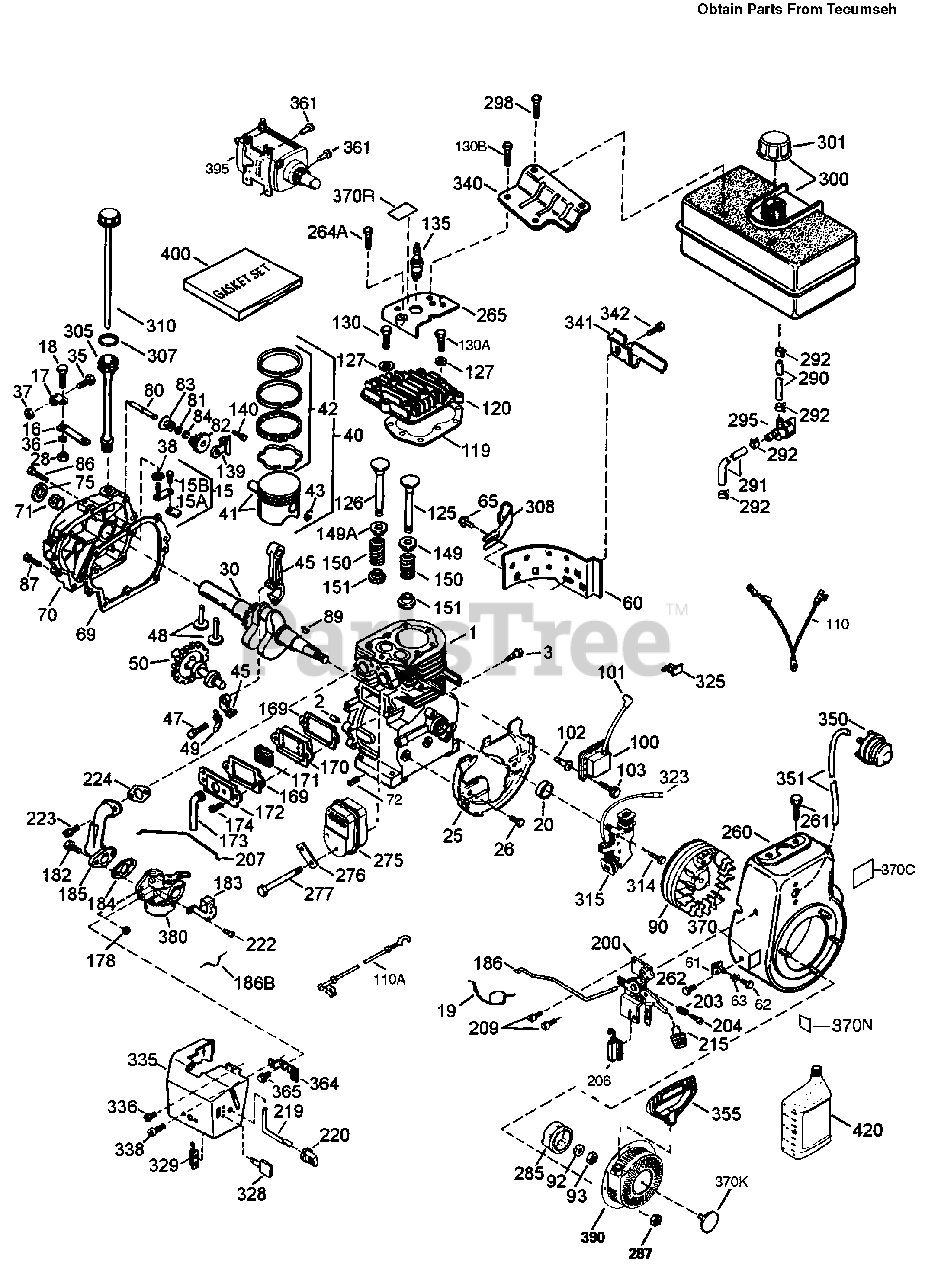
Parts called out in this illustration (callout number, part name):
1	Cylinder Asm (Incl. Ref. #2, 20, & 72)
2	Dowel Pin
15	Governor (Incl. Ref. #15A & 15B)
15A	Governor Yoke
16	Governor Lever
17	Governor Lever Clamp
19	Spring-Speed Control
20	Oil Seal
25	Blower Housing Baffle
28	Lock Nut
30	Crankshaft
36	Lock Washer
37	Lock Nut
38	Retaining Ring
40	Piston, Pin & Ring Set (Std.)
40	Piston, Pin & Ring Set (.010" OS)
41	Piston & Pin Asm (Std.)(Incl. Ref. #43)
41	Piston & Pin Asm (.010" OS)(Incl. Ref. #43)
42	Ring Set (Std.)
42	Ring Set (.010" OS)
43	Piston Pin Retaining Ring
45	Connecting Rod Asm (Incl. Ref. #47, & 49)
47	Connecting Rod Bolt
48	Valve Lifter
49	Oil Dipper
50	Camshaft (MCR)
60	Blower Housing Extension
61	Grommet Mounting Bracket
63	Grommet
69	Cylinder Cover Gasket
70	Cylinder Cover (Incl. Ref. #71, 75, & 80)
71	Crankshaft Bushing
72	Oil Drain Plug
75	Oil Seal
80	Governor shaft
82	Governor Gear Asm (Incl. Ref. #81)
83	Governor Spool
84	Retaining Ring
89	Flywheel Key
90	Flywheel (W/Ring Gear)
92	Lock Washer
93	Flywheel Nut
100	Solid State Ignition
101	Spark Plug Cover
102	Solid State Mounting Stud
103	Screw, Torx T-15
110	Ground Wire
110A	Ground Wire
119	Cylinder Head Gasket
120	Cylinder Head
125	Exhaust Valve (Std.)(Incl. Ref. #151)
125	Exhaust valve (1/32" OS)(Incl. Ref. #151)
126	Intake Valve (Std.)(Incl. Ref. #151)
126	Intake Valve (1/32" OS)(Incl. Ref. #151)
135	Resistor Spark Plug (RJ19LM)
139	Governor Gear Bracket
149	Valve Spring Cap
149A	Valve Spring Cap
150	Valve Spring
151	Valve Spring Keeper
169	Valve Cover Gasket
170	Breather Body
171	Breather Element
172	Valve Cover
173	Breather Tube
178	Nut & Lock Washer
183	Choke Bracket
184	Carburetor To Intake Pipe Gasket
185	Intake Pipe
186	Governor Link
186B	Spring-Choke
200	Control Bracket (Incl. Ref.#19, 203, 204 & 206)
203	Compression Spring
206	Terminal
207	Throttle Link
215	Control Knob
219	Choke rod
220	Choke Knob
223	Screw, Torx T-30
224	Intake Pipe Gasket
260	Blower Housing
262	Screw, Torx T-40
265	Cylinder Head Cover
275	Muffler
276	Locking Plate
285	Starter Cup
287	Nut & Lock Washer
290	Fuel Line
291	Fuel Line
292	Fuel Line Clamp
295	Fuel shut-Off Valve
300	Fuel Tank (Incl. Ref. #292 & 301)
301	Fuel Cap
305	Oil fill Tube
307	"O" Ring
308	Fill Tube Clip
310	Dipstick
315	Alternator Coil (18 Watt)(Incl. Ref. #323)
323	Terminal
325	Wire Clip
328	Ignition Keys
329	Terminal
335	Carburetor Cover
340	Fuel Tank Bracket
341	Fuel Tank Bracket
350	Primer Bulb
351	Primer Line
355	Starter Handle
361	Screw, Torx T-30
364	Carburetor Cover Bracket
370	Identification Decal
370C	Primer Decal
370K	Starter-Decal
370N	Bilingual Decal
370R	Warning Decal
380	Carburetor (Incl. Ref. #184)
390	Rewind Starter (Note: This engine could have been built with 590749 starter.)
395	Electric Starter Motor, 120 Volt (Optional)
400	Gasket Set
420	SAE 5W30 4-Cyc. Eng. Oil
